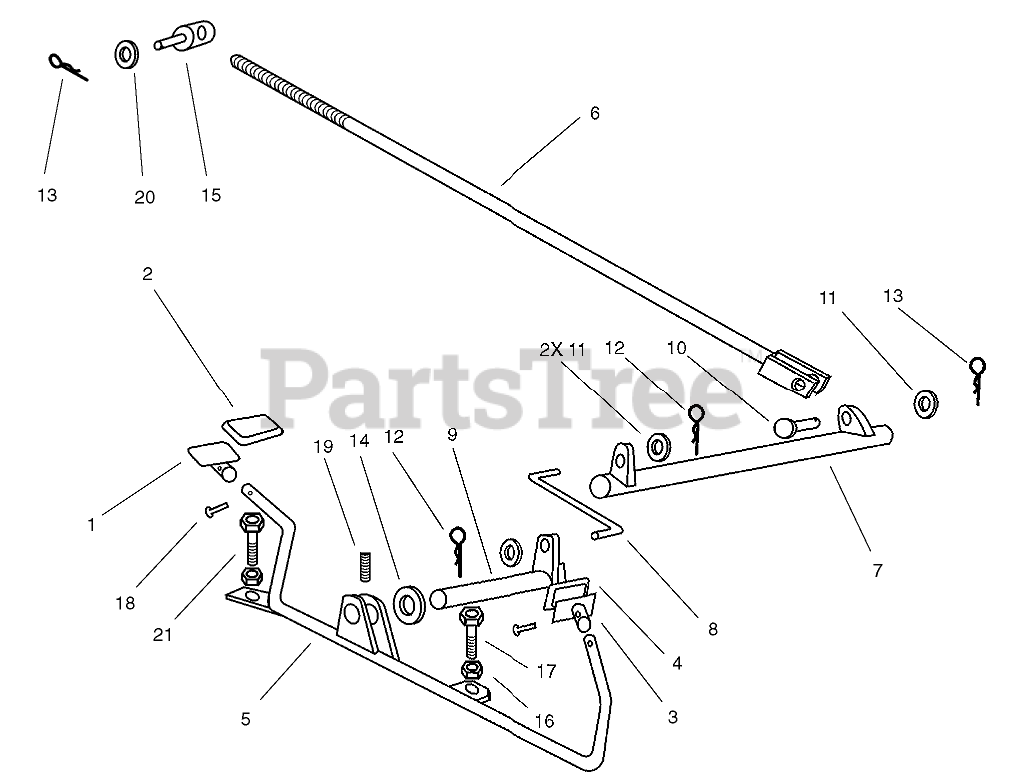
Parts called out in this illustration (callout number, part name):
1	PEDAL-REAR, TRAVEL
2	PAD-PEDAL
3	PEDAL-TRAVEL, FRONT
4	PAD-PEDAL, FRONT
5	ROD-TRAVEL
6	ROD-TIE
7	SHAFT-DIAGONAL
8	LINK-FORMED
9	SHAFT-DIAGONAL
11	WASHER-FLAT
12	PIN-COTTER
13	PIN-COTTER
14	SPACER
16	NUT-HEX
17	CAPSCREW-HH
18	PIN-SPRING
19	PIN-SPRING
20	WASHER
21	SCREW-HH
